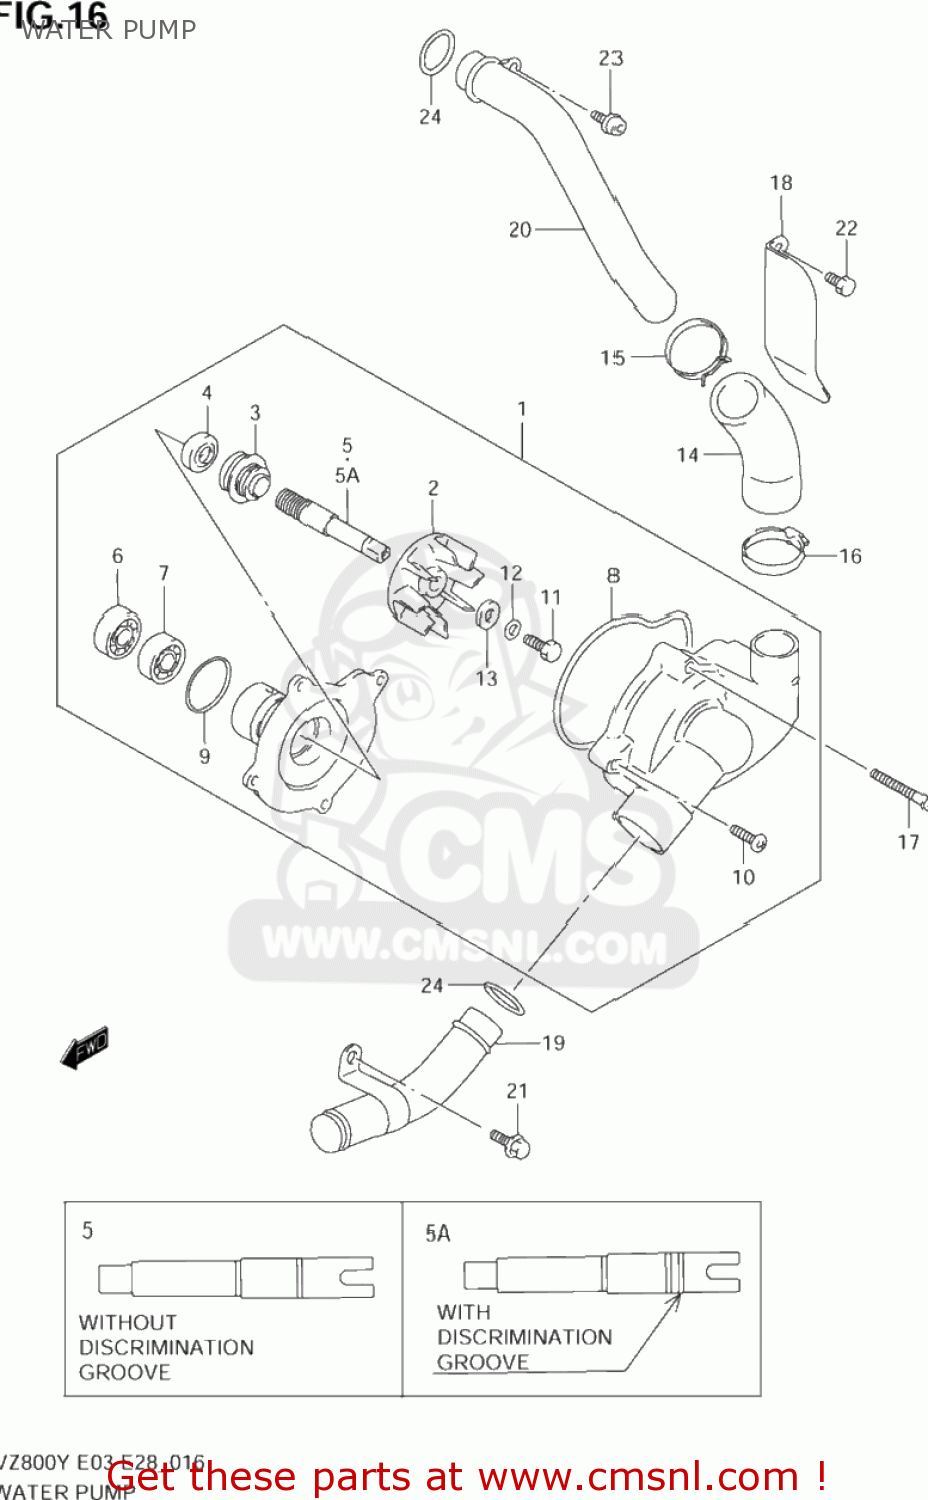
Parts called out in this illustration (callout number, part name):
1	PUMP ASSY,WATER
2	IMPELLER
3	SEAL,MECHANICAL
4	SEAL,OIL(10X21X5)
5	SHAFT
5A	SHAFT,WATER PUMP
6	BEARING(10X26X8)
7	BEARING(12X28X8)
8	O RING
9	O RING,WATER PUMP HOLDER
10	SCREW 6X16
11	BOLT(6X13)
12	WASHER
13	GASKET(6X15X2.2) (NAS)
14	HOSE,WATER PUMP OUTLET
15	CLAMP
16	CLAMP
17	BOLT
18	PLATE,WATER HOSE
19	PIPE,WATER PUMP INLET
20	PIPE,WATER PUMP OUTLET
21	BOLT
22	BOLT
23	BOLT
24	O RING(D:2.7,ID:21.4)
